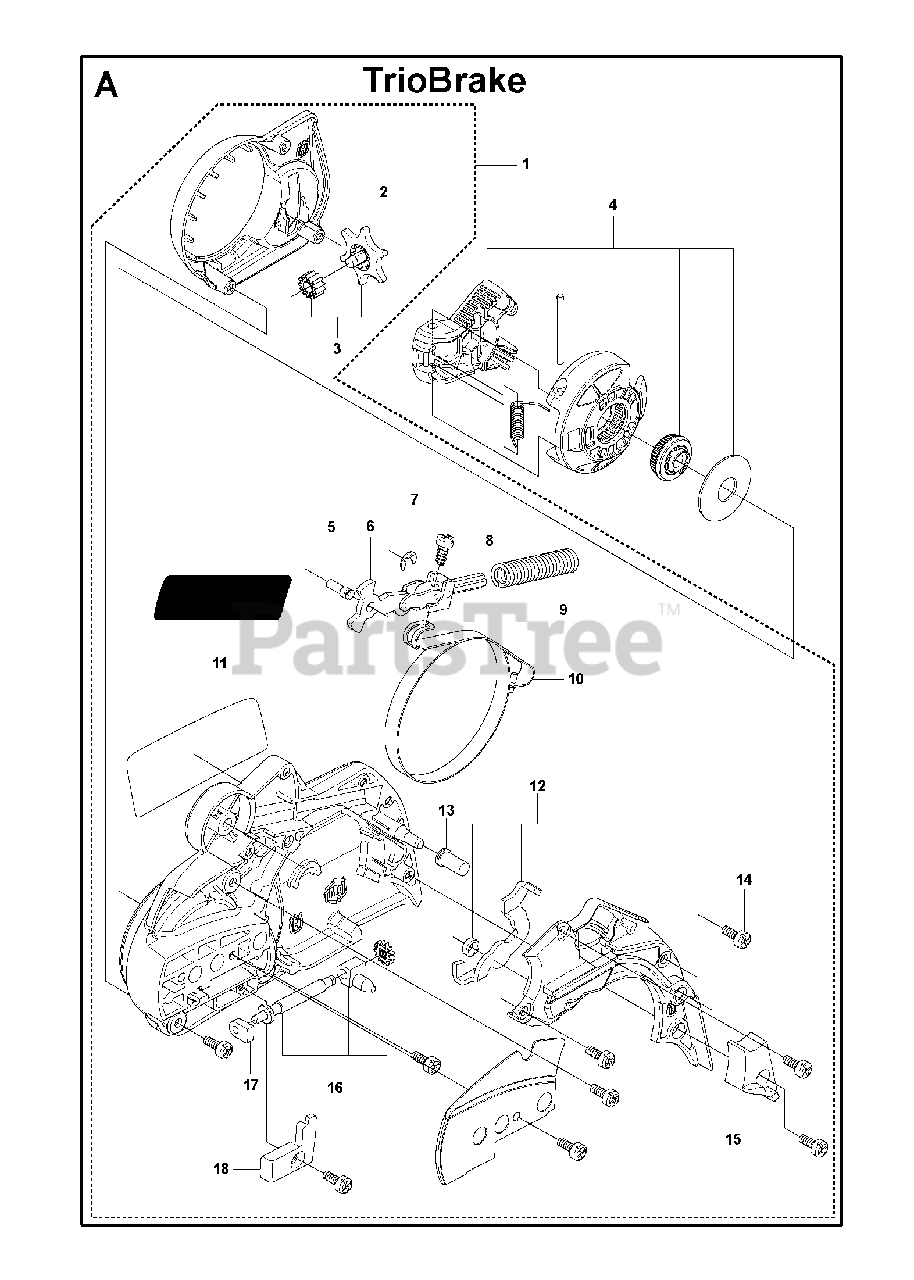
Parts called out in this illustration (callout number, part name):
1	CLUTCH COVER ASSY
2	HEAT SHIELD
3	CHAIN TENSIONER WHEEL, COMP.
4	KNOB, COMPLETE
5	PIN
6	JOINT
7	E-RING 4
8	SCREW
9	SPRING
10	BRAKE BAND
11	DECAL, CLUTCH HOUSING
12	COVER LID ASSY
13	SLEEVE
14	SCREW
15	WEAR GUARD, CHAIN
16	CHAIN TENSIONER SCREW, COMP.
17	RP BEARING SLEEVE
18	COVER
